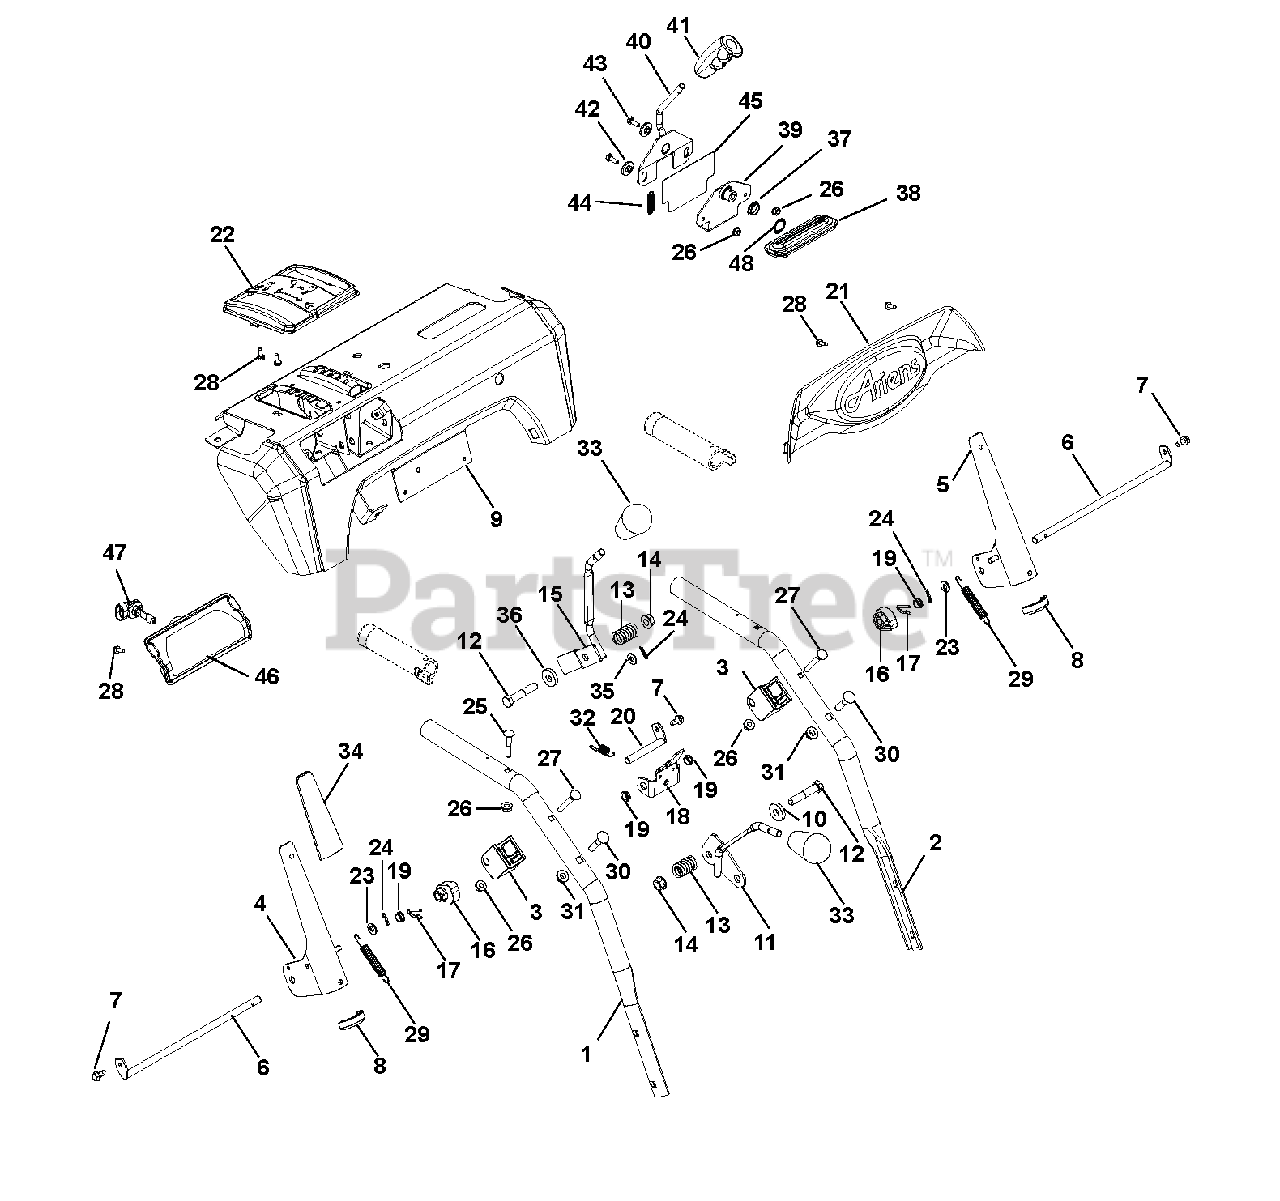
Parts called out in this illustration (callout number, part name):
1	HANDLEBAR, UPPER RH W/HW
2	HANDLEBAR, UPPER LH W/HW
3	BLOCK, CLUTCH PADDLE
4	LEVER, CLUTCH-RH
5	LEVER, CLUTCH-LH
6	ROD, PADDLE MOUNT - PRO
7	SCR-TAP .25-20X.50 HWH TR YWZ
8	EDGING, CLUTCH PADDLE - 2.00"
9	CONTROL PANEL W/DECAL, 12V
9	CONTROL PANEL W/DECAL QT,AD,HW
9	CONTROL PANEL W/DECAL QT,HW,TK
10	WSHR-FL-STL .406X1.00X.188 YWZ
11	WELDMENT, CONTROL LEVER(SHIFT)
12	@BLT-HEX .38-16X2.00 GR5 YWZC
13	SG-COMP .125X.781X1.250
14	@NUT-LK-TOP-FLG .38-16 YWZC
15	WELDMENT, CONTROL LEVER (DEFL)
16	CAM, INTERLOCK
17	PIN, SPRING CLIP
18	BRACKET, INTERLOCK ARM
19	BUSHING, POLYLINER-.38 SNAPIN
20	ROD, PIVOT - INTERLOCK
21	DASH BEZEL, ARIENS LOGO - PRO
22	BEZEL, SHIFT
23	@WSHR-FL-STL.281X.62X.065 YWZC
24	PIN-HAIR INT .06X.18X.77
25	BLT-RDHDXLSQNK.25-20X1.25 G5ZC
26	@NUT-LK-CTR-FLG .25-20 YWZC
27	BLT-RDHDXLSQNK .25-20X2.0 G5YZ
28	SCR-TAP #10X.50 BOSS INDHXHD
29	SPRING, EXTENSION
30	@BLT-RDHDSQNK .31-18X1.50 G5YZ
31	@NUT-LK-TOP-FLG .31-18 YWZC
32	SPRING-EXT .047X.438X1.45
33	KNOB,SOFT TEARDROP,PUSH-ON GRY
34	CLUTCH PADDLE SLEEVE - GRAY
35	BSHG-SLV .265X.500X.219
36	WSHR-FL-STL .380X1.50X.062 YWZ
37	BUSHING, POLYLINER-.75 SNAPIN
38	GROMMET-BOOT, QUICKTURN
39	MOUNT, CHUTE CONTROL
40	LEVER, CHUTE CONTROL
41	CONTROL HANDLE, QUICK TURN
42	BSHG-FLG .265X.448X.243X1.00
43	@BLT-HEX .25-20X.75 GR5 YWZC
44	SG-TENS .048X.44X1.75 WLD 9
45	TAPE, DIE CUT - QUICK TURN
46	HEADLIGHT ASSY, HALOGEN 20W
47	BULB, LIGHT-HALOGEN 20W
48	NUT, PUSH -.75" SHAFT
